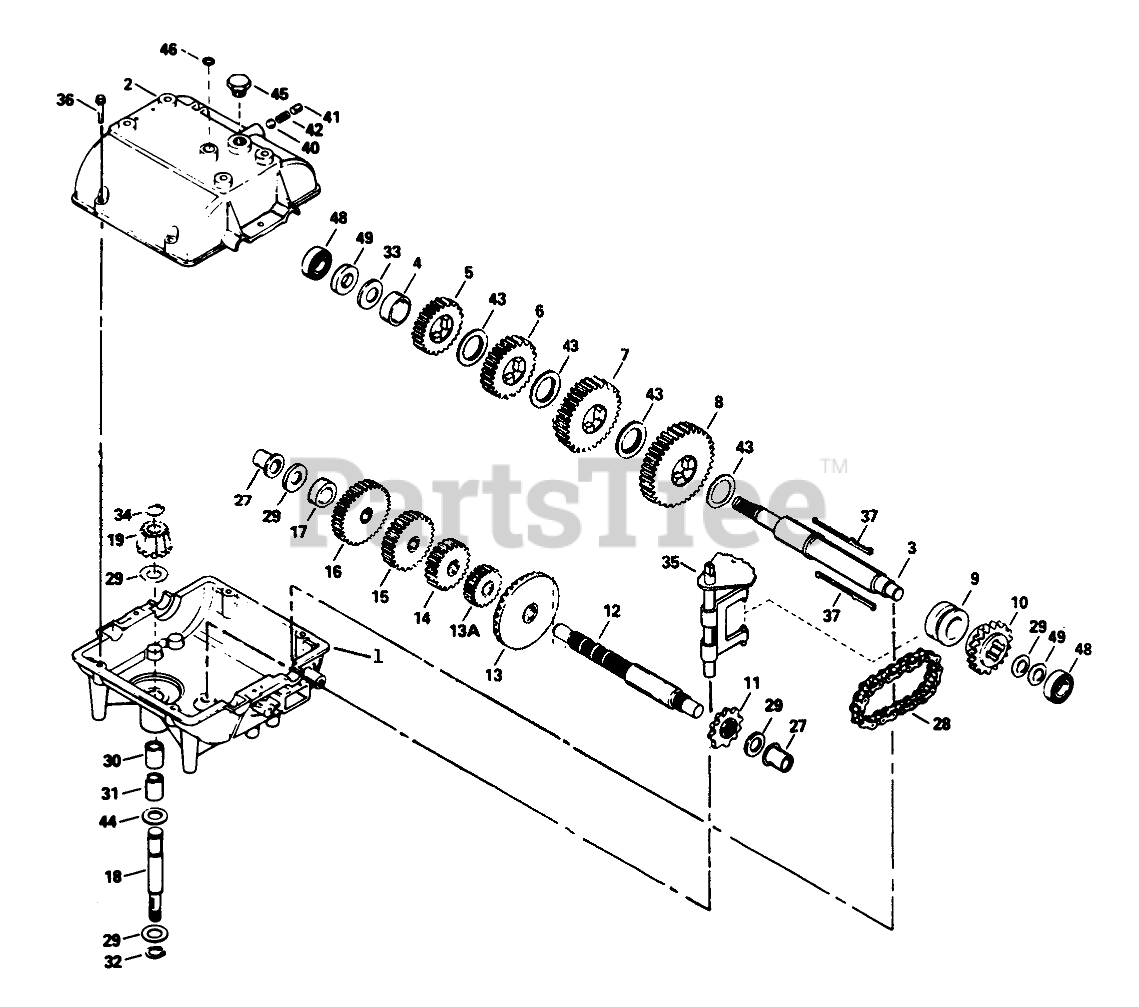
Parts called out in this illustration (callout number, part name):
1	Case-Transmission
2	Cover-Transmission
3	Shaft-Output/Brake
4	Spacer
5	Gear-Spur, 25 Teeth
6	Gear-Spur 27 Teeth
7	Gear-Spur, 30 Teeth
8	Gear-Spur, 35 Teeth
9	Collar-Shift
10	Sprocket-18 Teeth
11	Sprocket-9 Teeth
12	Countershaft
13	Gear-Bevel, 42 teeth
13A	Gear-Spur 15 Teeth
14	Gear-Spur, 20 Teeth
15	Gear-Spur 23 Teeth
16	Gear-Spur, 25 Teeth
17	Spacer
18	Shaft-Input
19	Bevel Pinion-Input
27	Bushing-Flange
28	Chain-Roller #41
29	Washer
30	Bearing-Needle
31	BeARing-Needle
32	Ring-Snap
33	Washer
34	Ring-Retainer
35	Rod and Fork ASM
36	Ring Set (.020 O S)
40	Ball-Steel
41	Screw-Set
42	Spring
43	Washer
44	O Ring
46	Cut Seal-Square
48	Bearing-Ball
49	Thrust Washer
